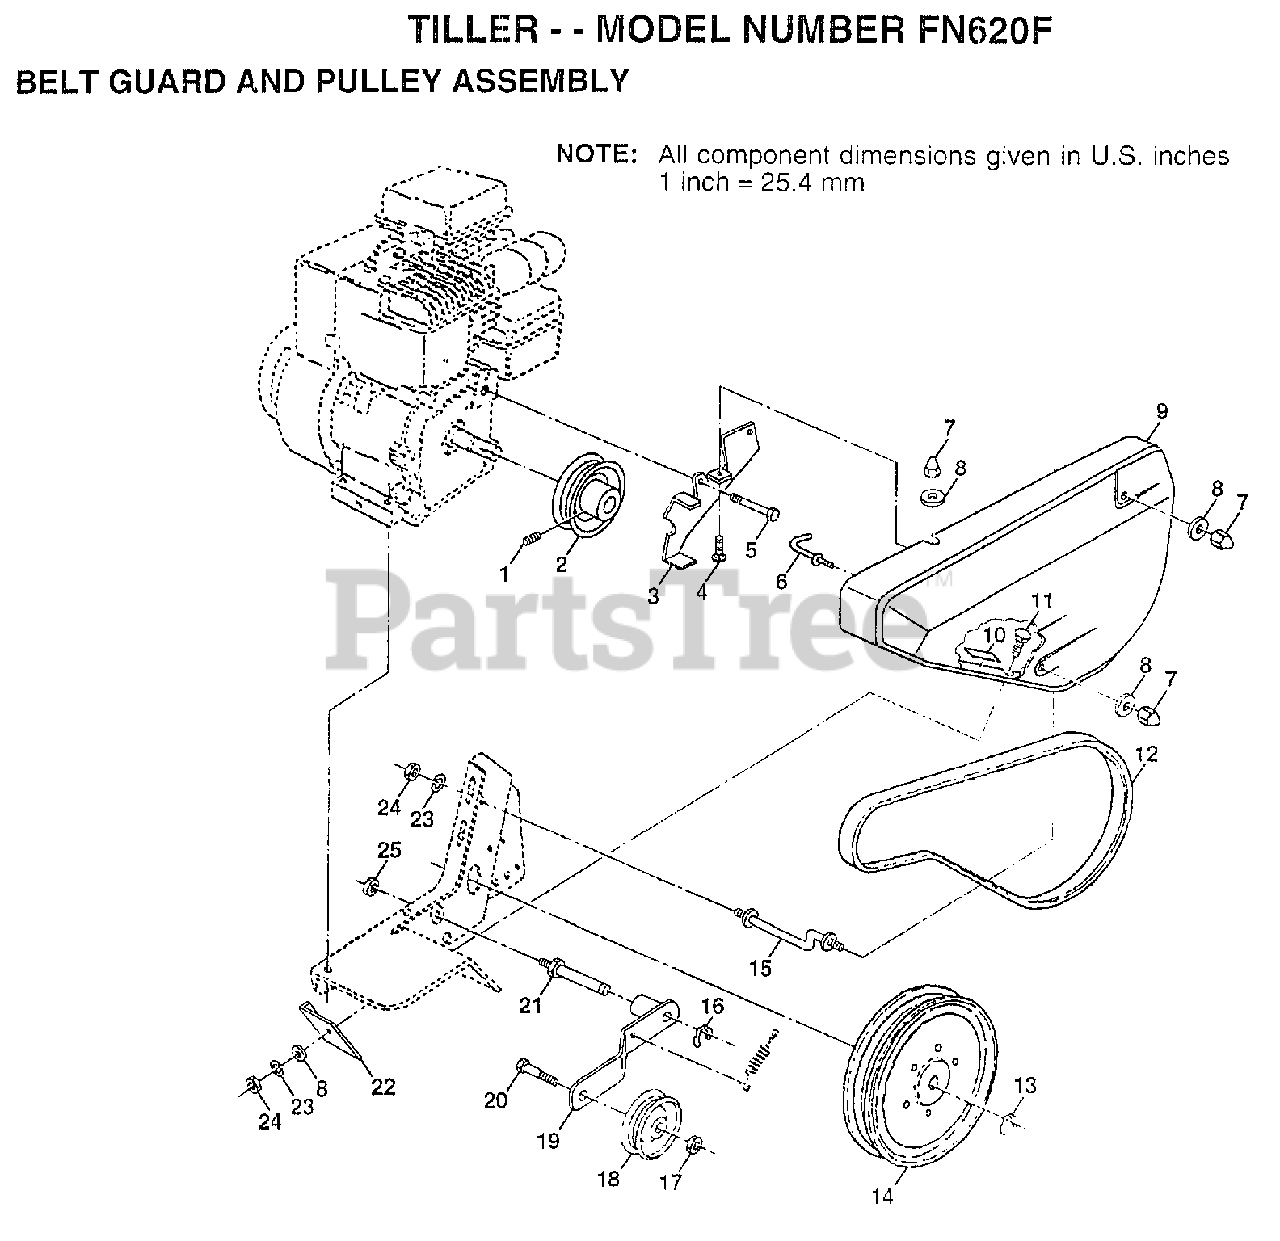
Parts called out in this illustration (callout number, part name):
1	SET SCREW
4	BOLT
5	BOLT.HEX.HEAD
7	NUT-CAP TI
8	WASHER
10	PAD IDLER TI
11	BOLT T
14	PULLEY.TRANSMISSN
16	KLIP RING TI
17	NUT
18	"PULLEY,IDLER"
19	"ARM, IDLER"
21	SHAFT IDLER TI
22	SHIELD-DIRT TI
23	LOCKWASHER
25	JAM NUT TI
